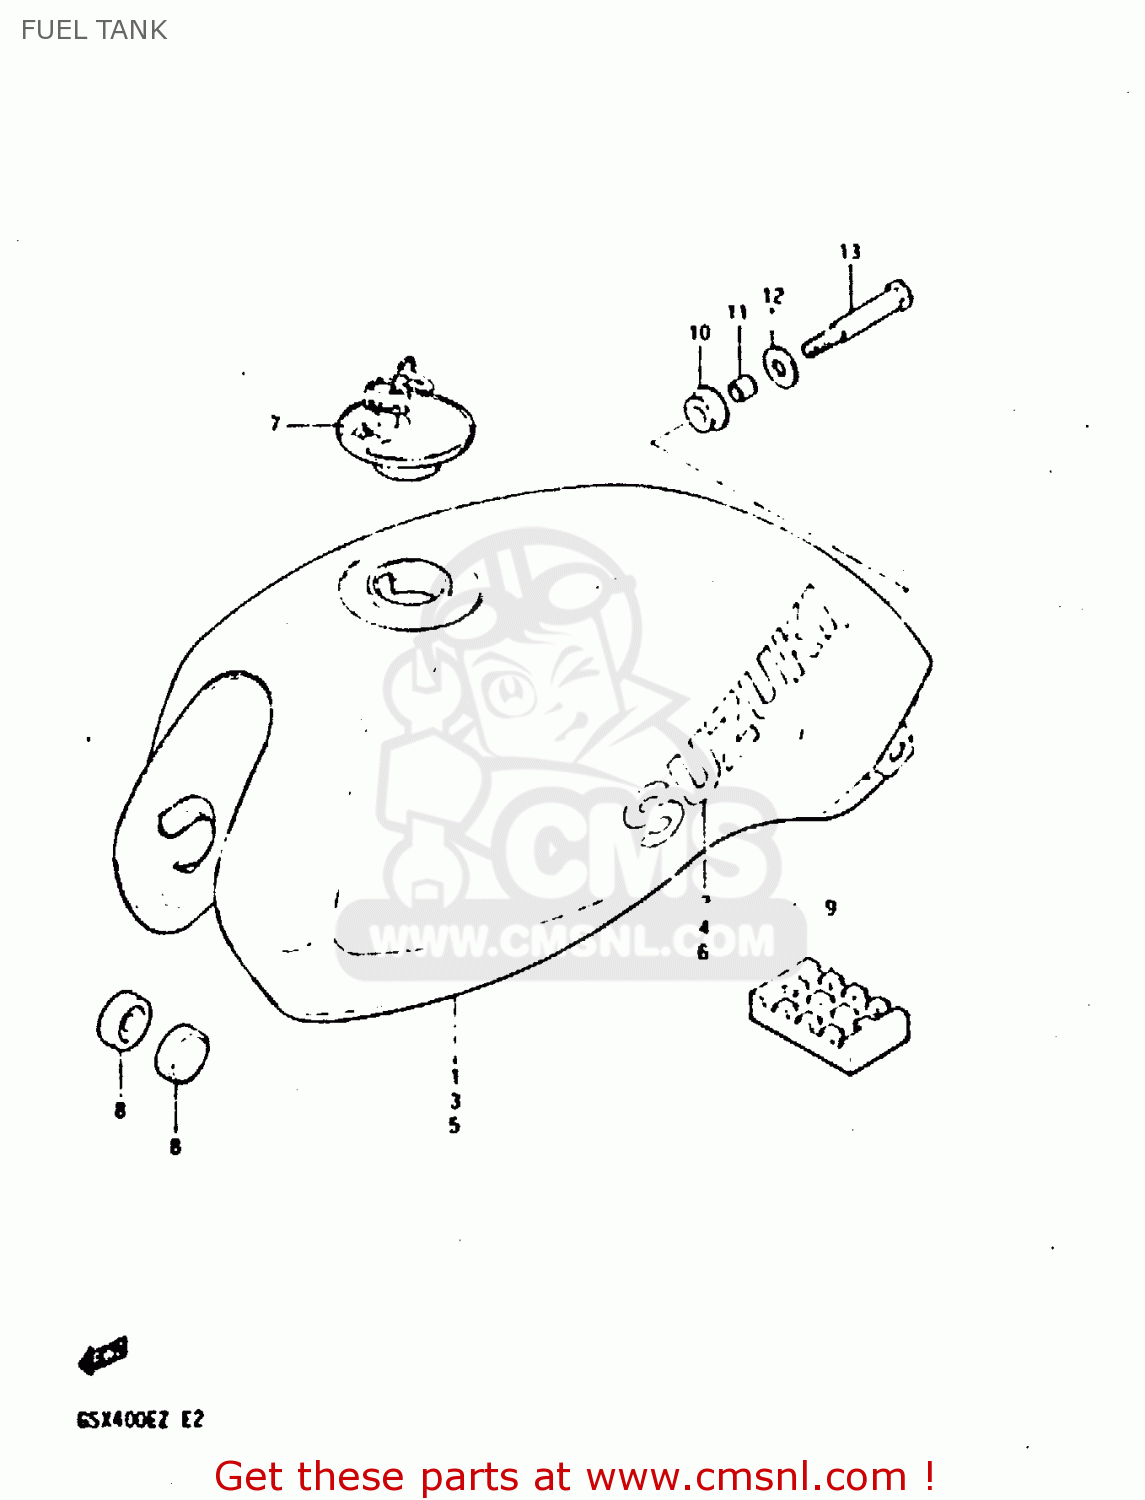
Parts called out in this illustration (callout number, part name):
1	TANK ASSEMBLY,FUEL
2	EMBLEM(SILVER)
3	TANK, FUEL (SILVER)
4	EMBLEM(ORANGE)
5	TANK, FUEL (BLACK)
6	EMBLEM(SILVER)
7	CAP SET,FUEL TANK
8	CUSHION
9	CUSHION,FUEL TANK CTR
10	CUSHION
11	SPACER (6.8X10X10)
12	WASHER (6.5X29X1.6)
13	BOLT(6X60)
